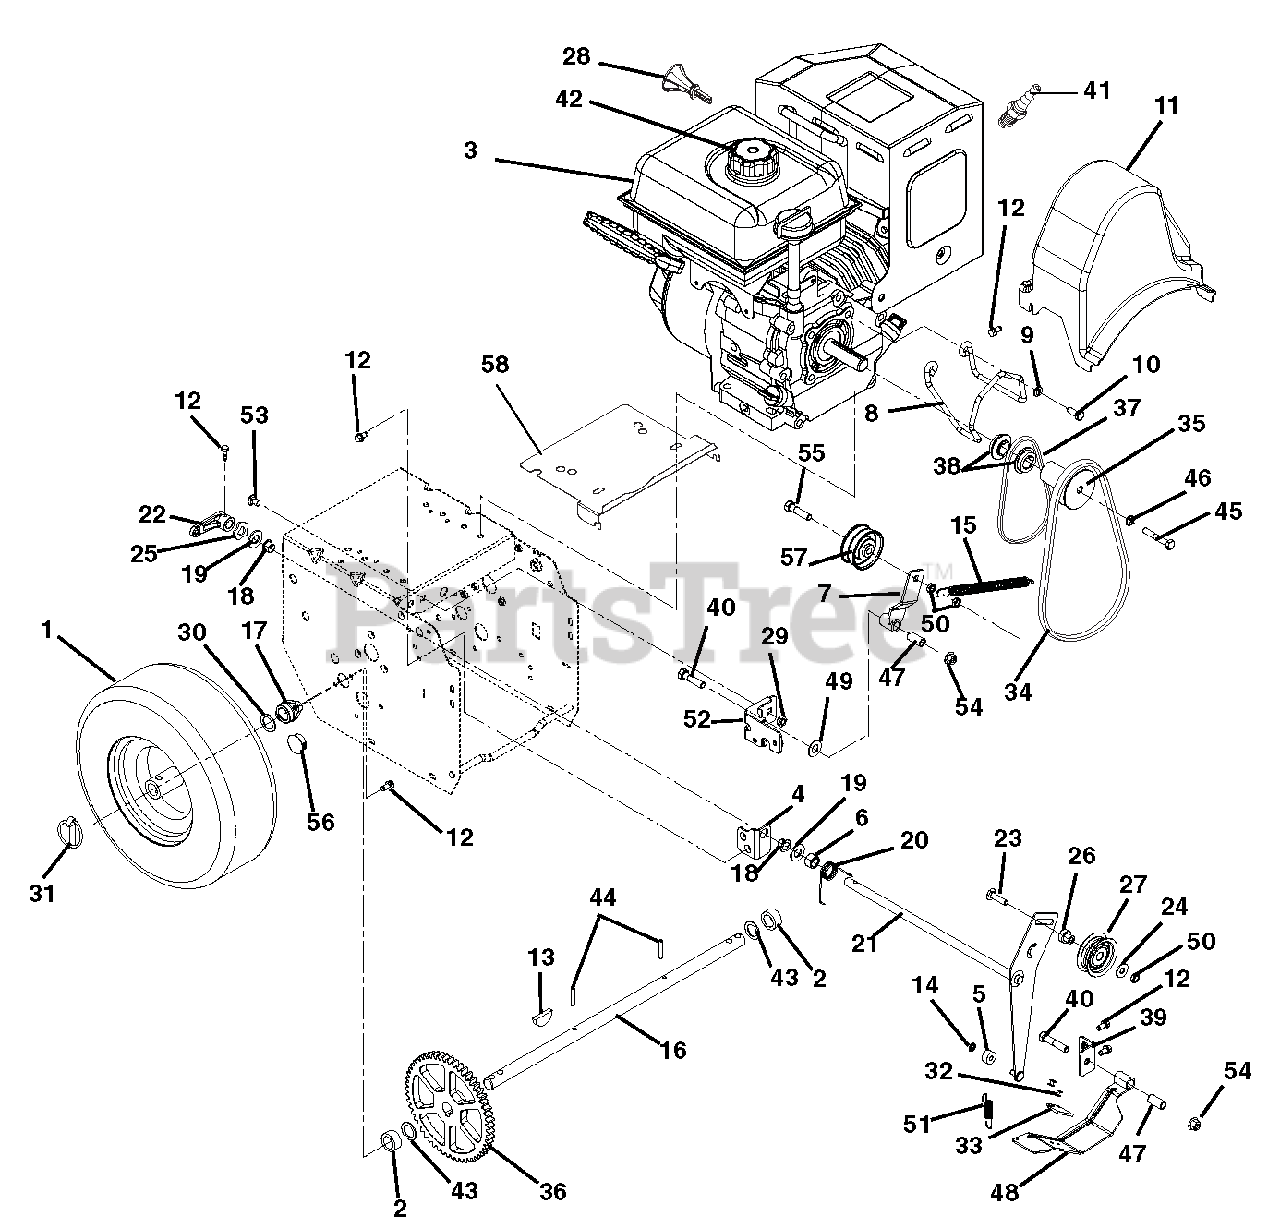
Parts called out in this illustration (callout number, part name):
1	TIRE/WHEEL, 13X4.10-6 K398A
1	TIRE/WHEEL, 15X5.00-6 K398A
1	TIRE, 13" K398A
1	TIRE, 15" K398A
2	BSHG-SLV .766 X 1.125 X .500
3	ENGINE,LCT STORMFORCE 208 RECL
4	BRACKET, MOUNT - IDLER ARM
5	BSHG,SLV .265 X .625 X .375
6	BSHG-SLV .510X.751X.475
7	WELDMENT, TRACTION IDLER ARM
8	FINGER, BELT
9	WSHR-LK .312X.097 HVY YWZC
10	BLT-HEX .31-24X.75 YWZC GR5
11	COVER, COMPACT BELT
12	SCR-TAP .25-20X.50 HWH TR YWZ
13	KEY-WDRF .25X.750X.313 SAE91
14	RG-RTNG-EXT .250X.010
15	SG-TENS .062X.56X8.0 WLD 11
16	SHAFT, AXLE
16	AXLE, COMPACT 920,XXX 15" TIRE
17	BSHG .75X1.125X.65
18	BUSHING, POLYLINER-.50 SPLIT
19	@WSHR-FL-STL.531X1.06X.095YWZC
20	SG-TORS .075 X .955
21	WELDMENT, ATTACHMENT IDLER ARM
22	ARM, CLUTCH - ATTACHMENT
23	@BLT-RHDSHSQNK.31-18X1.25 G5YZ
24	@WSHR-FL-STL.38X.875X.083 YWZC
25	WSHR-WAVE .50X.75X.015 .13FRHT
26	SPCR, BRG .315X.50X.688X.281
27	IDLER
28	KEY, PUSH/PULL LCT (2/PACKAGE)
29	@NUT-LK-TOP-FLG .31-18 YWZC
30	WSHR-FL-STL.754X1.125X.062YWZC
30	BSHG-SLV .75X1.12X1.062 NYL BK
31	PIN-LOK .31X1.75
32	RVT-POP .187 YZ
33	PAD, BRAKE
34	V-BELT, HA-RAW EDGE
35	SHEAVE, AUGER .75ID 920,XXX LG
36	SPUR GEAR, 54T .75ID X 6.75PD
37	V-BELT, 3L-WRAPPED
38	TRACTION SHEAVE HALF
39	BRACKET, MOUNT - BRAKE
40	@BLT-HEX .38-16X1.75 GR5 YWZC
41	PLUG, SPARK
42	CAP, FUEL TANK BLACK
43	WSHR-FL-STL.754X1.125X.062YWZC
44	PIN-ROLL .188X1.25
45	BLT-HEX .38-24X2.0 YWZC
46	@WSHR-LK .38X.094 REG YWZC
47	BSHG-SLV .385X.500X1.045
48	BRAKE ARM W/PAD
49	@WSHR-FL-STL.406X.812X.065 YWZ
50	@NUT-LK-CTR-JAM .31-18 YWZC
51	SPRING-EXT .437 X .438 X 2.64
52	WELDMENT, FRAME BRACKET
53	@BLT-RHDSSQNK .31-18X.62 G5YZ
54	@NUT-LK-TOP-FLG .38-16 YWZC
55	@BLT-HEX .31-18X1.50 GR5 YWZC
56	PLUG, HOLE - 1.00" FLEXTEMP
57	IDLER,1.875" OD
58	BAFFLE,ENGINE,SMALL BLOCK
